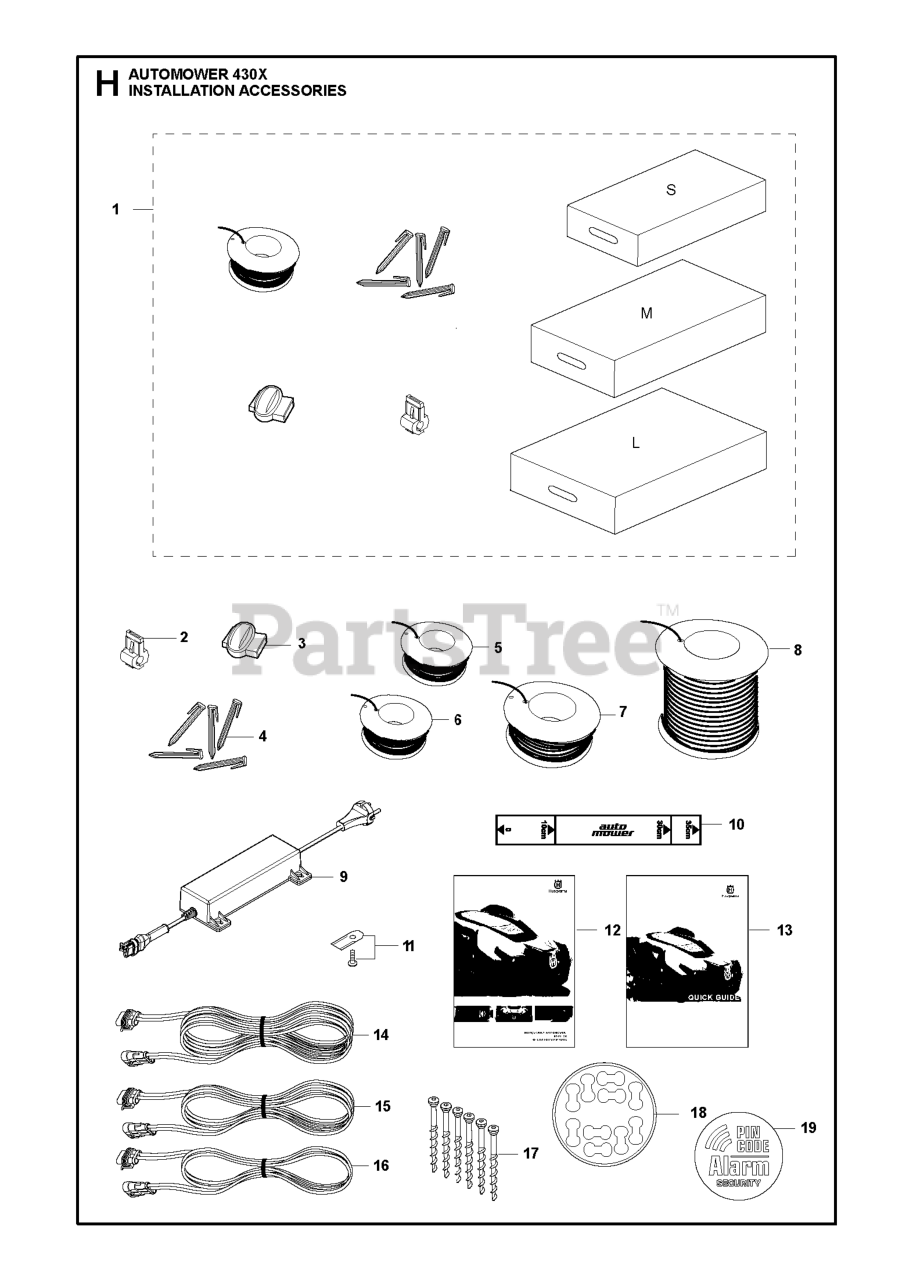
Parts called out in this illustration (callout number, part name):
2	SQUARE KEY
15	WASHER
17	SPRING.BRAKE.HG3000/3500
22	ROD.SHIFT.FENDER.TLT.2006
23	KNOB.DELUXE.(PISTOL.GRIP).BLAC
29	ROD.BRAKE.HG-0510
35	ROD.CNTRL.PARK.PREDATOR.LT.TEX
42	PEDAL COVER T
50	IDLER.FLAT.910.OFFSET
51	NUT LOCK FLG 3/8-16 UNC
52	IDLER.V-GROOVE.910.OFFSET
64	SHAFT.ASM.PEDAL.BRAKE.
70	CONSOLE SHIFT
73	BOLT HEX 5/16-18 GR 5
74	SCREW.HI-LO.CONSOLE
114	NUT.71038.31-18.HEX.NYLOCK
116	NUT LOCK HEX FLANGE 5/16-18
125	SCREW
143	Screw 5/16-18 x 1/2 Hex, Self Tapping 5/16-18 x 1/2
159	COTTER PIN
160	RETAINER CLIP
161	SPRING.RETURN.CLUTCH.2006
162	SPACER.TRANSAXLE.18&22
165	BUSHING.SHAFT.BRAKE.HAND
166	NUT.PUSH.625.2006
167	LATCH.BRAKE.SPRING
169	BOLT.HEX.FLNG.5/16-18X3.75
170	KEEPER.V-IDLER.CENTER.
172	STRAP.TRQ.LH.FS.HG0510
173	STRAP TORQUE RH
174	NUT.PUSH.500.2006
175	SHAFT.ASM.SHFT.HG0510/
176	ARM.CLEVIS.ROD.SHIFT
178	SPRING.SHIFT.GT2006
183	SPACER AXLE
184	HANDLE PARKING BRAKE
186	SPACER.RETAINER
187	WASHER 12/32X2X10GA
188	RP.LINK.CLUTCH.GROUND.DRIVE
189	BELLCRANK.GROUND.DRIVE.TEX.
190	KEEPER.BELLCRANK.DRIVE
195	BRKT.ROD.BRAKE.18/20/2
200	NUT.CENTERLOCK.5/16-
201	BOLT SHOULDER 5/16-18 UNC
202	LINK TRANS
203	WASHER
216	BRACKET.PULLEY.IDLER.W/TEX
221	RETAINER.SPRING.CLIP.H
240	IDLER.V-GROOVE.1.688.OFFSET
276	BOLT FIN HEX 7/16-14 X 1
277	WASHER SERRATED
